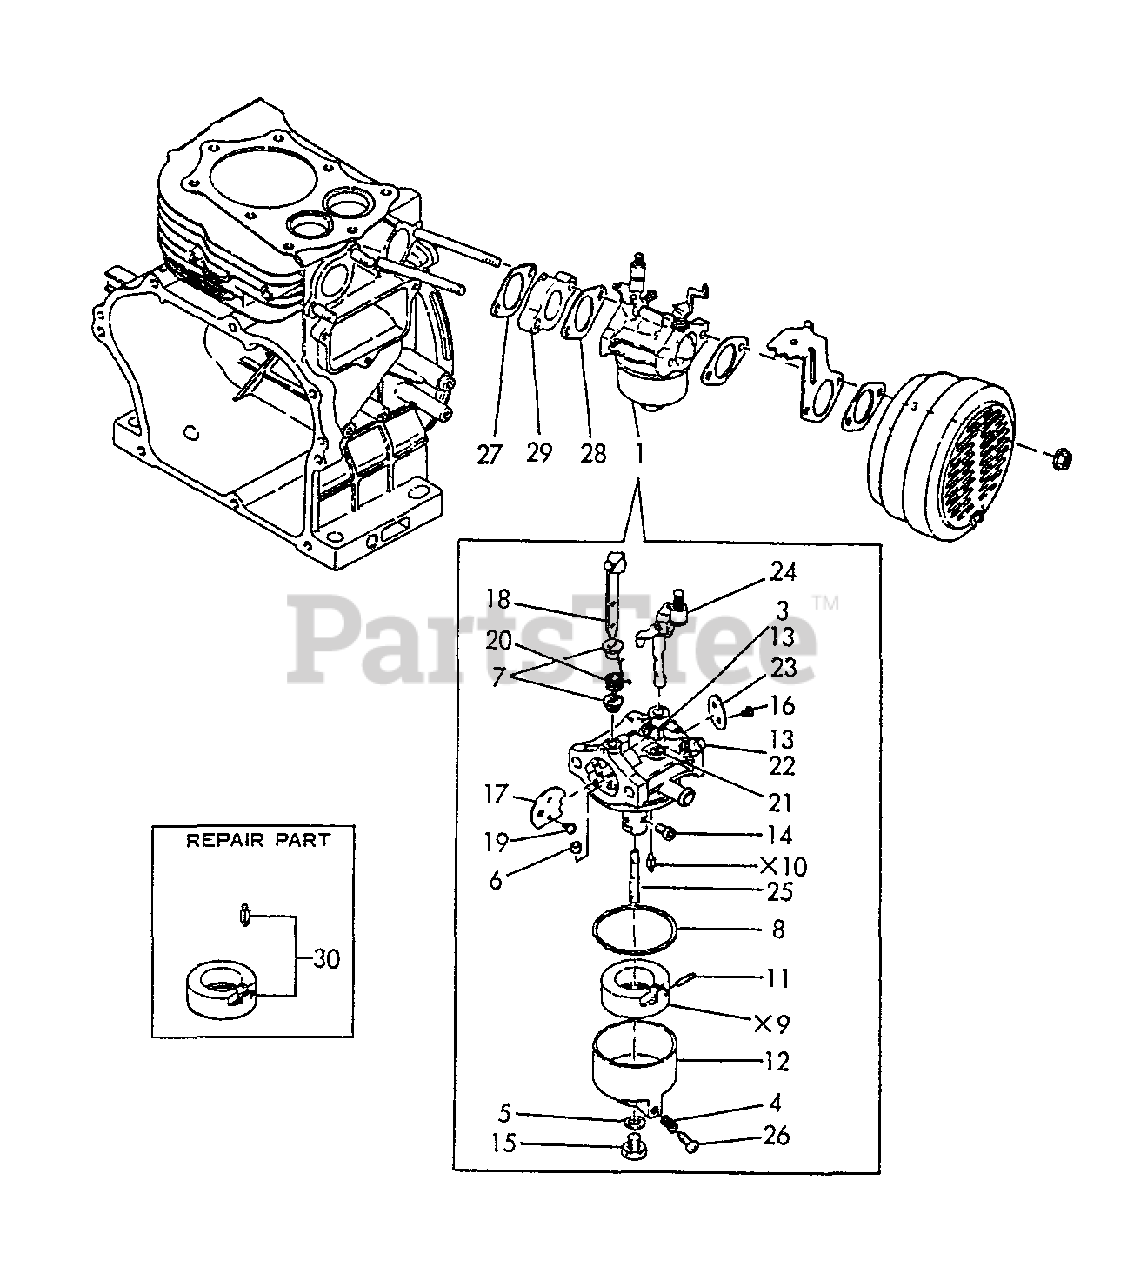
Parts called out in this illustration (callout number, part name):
1	CARBURETOR
3	SCREW
6	RING, CHOKE SHAFT
7	RING, CHOKE LEVER
9	FLOAT
10	NEEDLE
11	PIN
12	BODY
13	SPRING
14	JET, MAIN
15	BOLT
16	SCREW
17	VALVE, CHOKE
18	LEVER
20	SPRING, CHOKE
21	JET, PILOT
22	SCREW, PILOT
23	VALVE, THROTTLE
24	THROTTLE SHAFT ASSY
25	NOZZLE, MAIN
26	SCREW
29	SPACER
30	NEEDLE ASSY (RUBBER)
